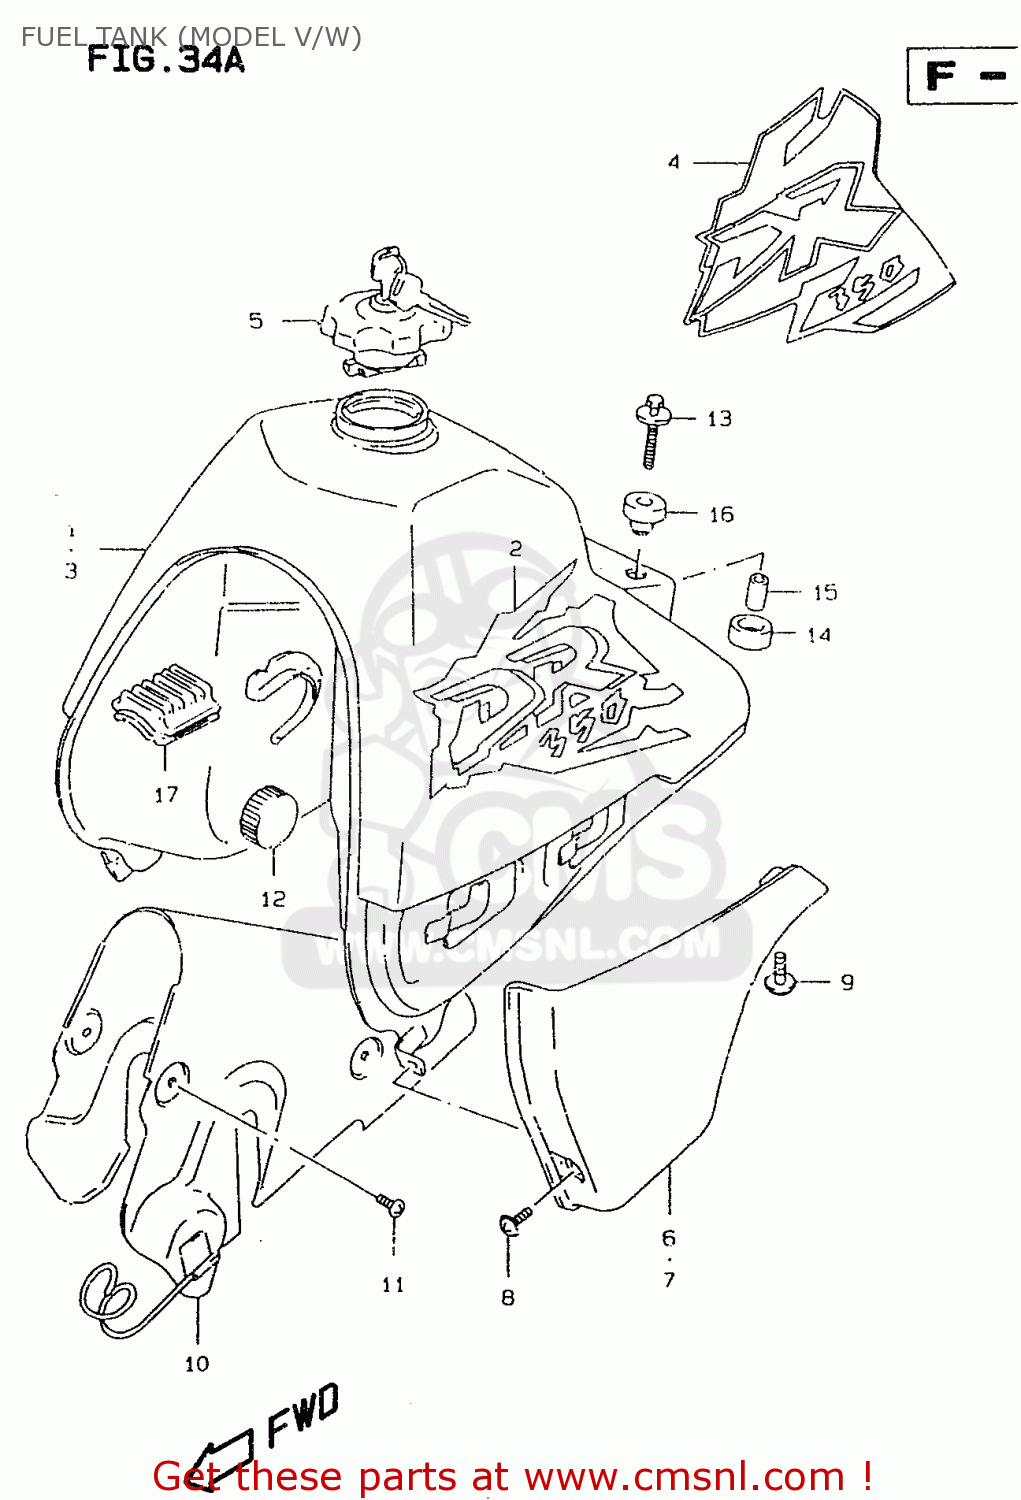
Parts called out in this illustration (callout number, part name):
1	TANK ASSY, FUEL (WHITE)
2	TAPE SET,FUEL TANK
3	TANK ASSY, FUEL (BLACK)
4	TAPE SET,FUEL TANK
5	CAP SET,FUEL TANK
6	COVER,FUEL TANK,R
7	COVER,FUEL TANK,L
8	SCREW(6X12)
9	SCREW
10	SHIELD,FUEL TANK
11	BOLT
12	CUSHION
13	BOLT(6X30)
14	CUSHION
15	SPACER(6.5X9X18)
16	CUSHION
17	CUSHION,FUEL TANK FR UPR
